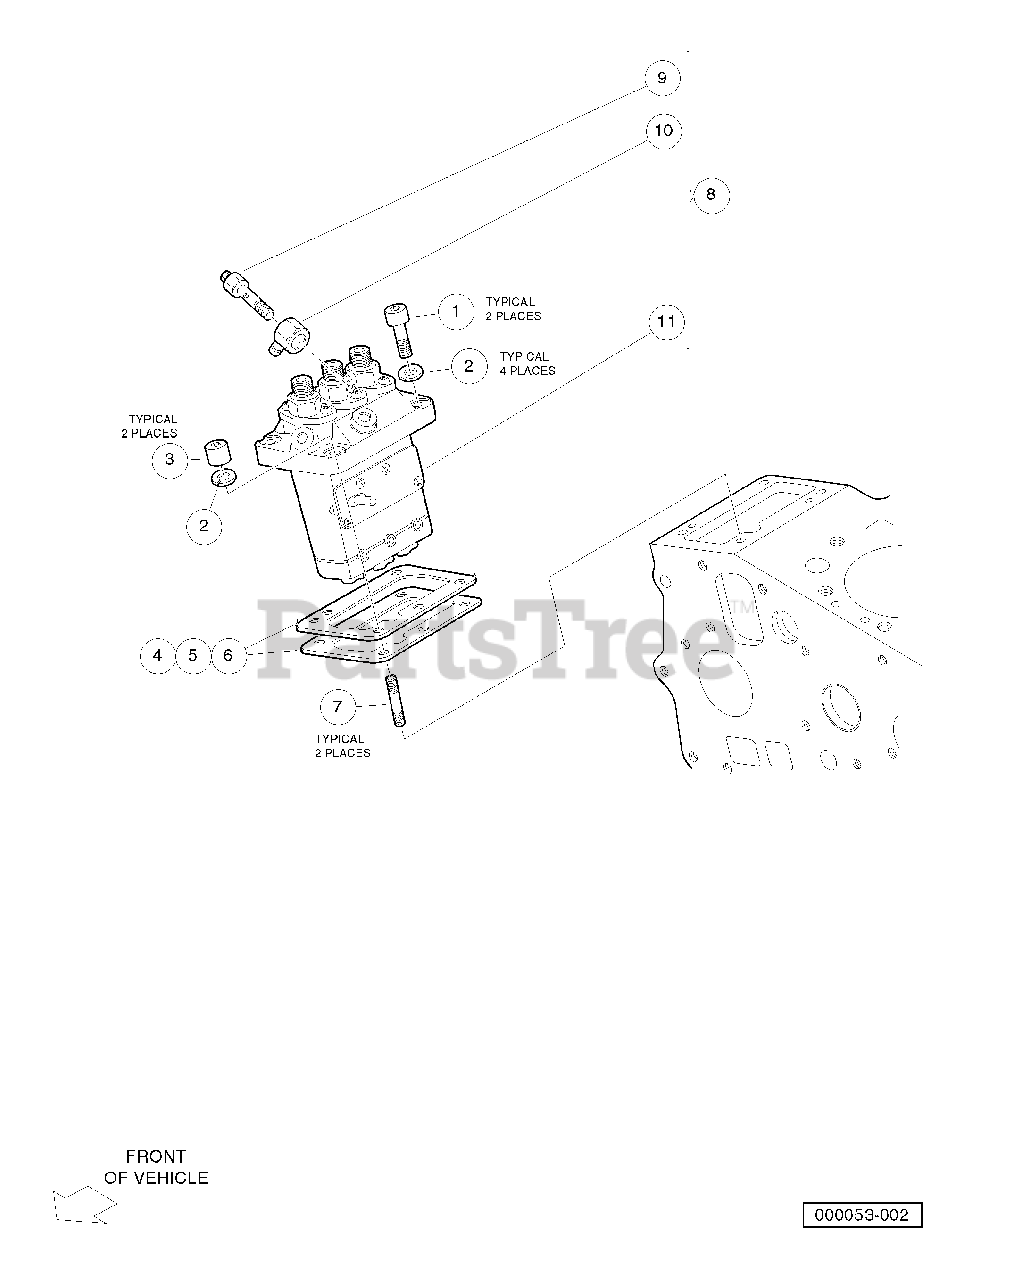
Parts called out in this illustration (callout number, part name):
1	Bolt, Hex-Head, M5 X 0.75 X
2	Washer, Spring, M6, D722
3	Nut, Special
4	Shim, Injection Pump, 0.20 mm
5	Shim, Injection Pump, 0.25 mm
6	Shim, Injection Pump, 0.30 mm
7	Stud, M5 X 25
8	Assembly, Fuel Injection Pump
9	Screw, Hollow, D722, Inj Pump
10	Joint, Eye
11	Pump, Injection
